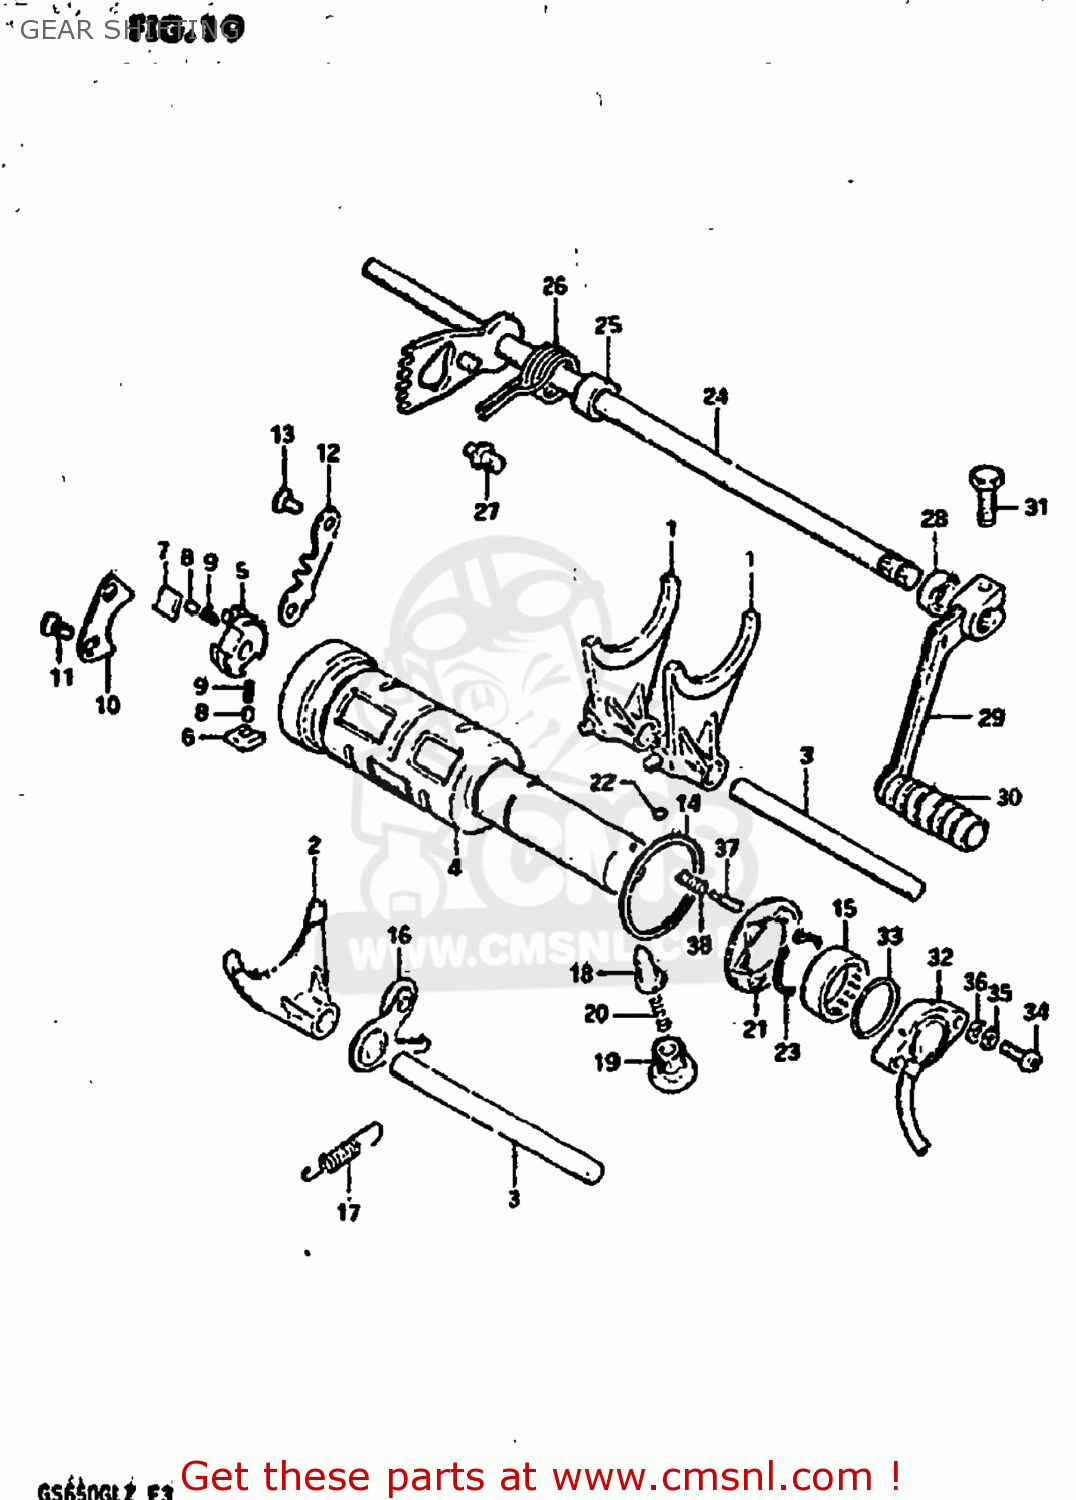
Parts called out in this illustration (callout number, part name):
1	FORK,GEAR SHIFT NO.1
2	FORK,GEAR SHIFT NO.3
3	SHAFT,GEAR SHIFT FORK
4	CAM,GEAR SHIFT
5	SHIFTER,GEAR SHIFT CAM
6	PAWL,GEAR SHIFT NO.1
7	PAWL,GEAR SHIFT NO.2
8	PIN(5X8)
9	SPRING
10	LIFTER,GEAR SHIFT PAWL
11	SCREW
12	GUIDE,GEAR SHIFT
13	SCREW
14	WASHER(40X45X1)
15	BEARING
16	STOPPER,GEAR SHIFTING
17	SPRING
18	STOPPER,GEAR SHIFT CAM NO.2
19	HOLDER,GEAR SHIFT CAM STOP SPR
20	SPRING
21	PLATE,GEAR SHIFT CAM STOPPER
22	PIN 4X6
23	CIRCLIP
24	SHAFT,GEAR SHIFT
25	SPACER(12X20X15.3)
26	SPRING
27	STOPPER,GEAR SHIFT CAM
28	OIL SEAL
29	LEVER ASSEMBLY,GEAR SHIFTING
30	RUBBER,GEAR SHIFT PEDAL
31	BOLT
32	TERMINAL BASE ASSY,GEAR SHIFT
33	O-RING (D:2.4 ID:26.2)
34	SCREW 5X20
35	LOCK WASHER
36	WASHER
37	PIN(5X15.5)
38	SPRING
